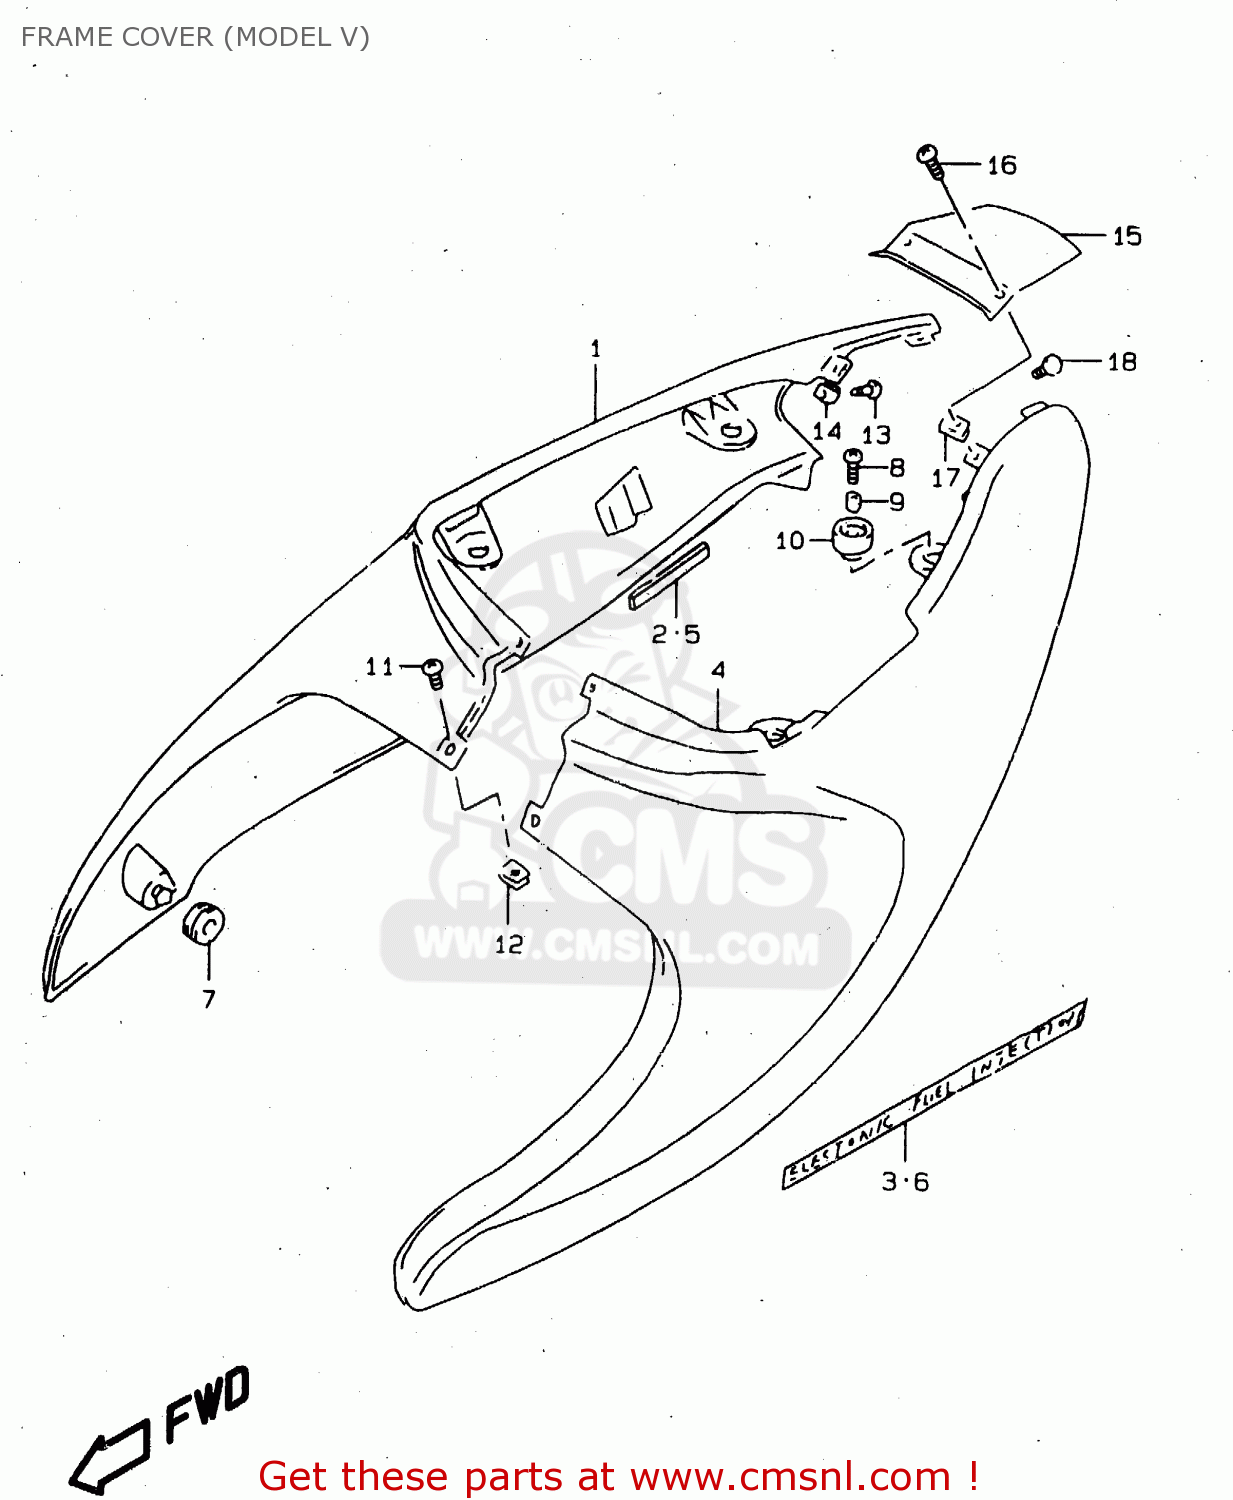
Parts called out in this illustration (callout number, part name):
1	COVER,FRAME,R(RED)
2	CUSHION,FRAME COVER
3	EMBLEM,FRAME COVER
4	COVER,FRAME,L(RED)
5	CUSHION,FRAME COVER
6	EMBLEM,FRAME COVER
7	CUSHION
8	SCREW(6X20)
9	SPACER(6.5X10X9.4)
10	CUSHION
11	SCREW L:12
12	NUT
13	SCREW(5X16)
14	NUT
15	COVER,FRAME CTR
16	SCREW
17	NUT
18	CUSHION
